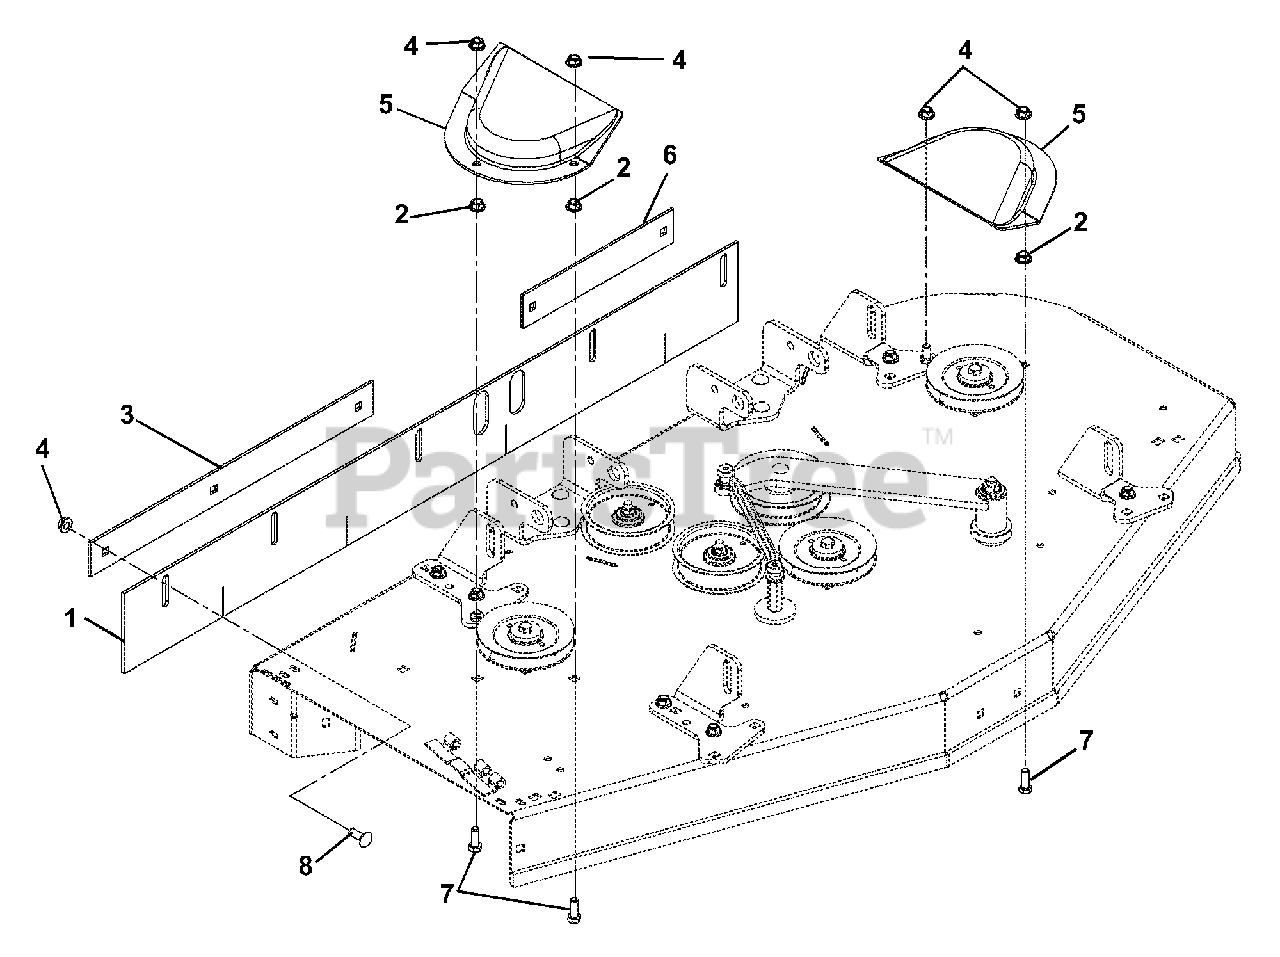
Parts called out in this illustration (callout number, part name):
1	Striper, Rubber 48"
1	Striper, Rubber 44"
2	Nut, Locking Top Flange .38-16
3	Bar, Retaining Stripper 44"
3	Bar, Retaining Stripper 48"
4	Nut, .38-16 Flange Nyloc
6	Bar, LH Retaining Stripper
7	Bolt, Hex .38-16 x 1.00
8	Bolt, Round Head Square Neck .38-16 x 1.00 Grade 5
